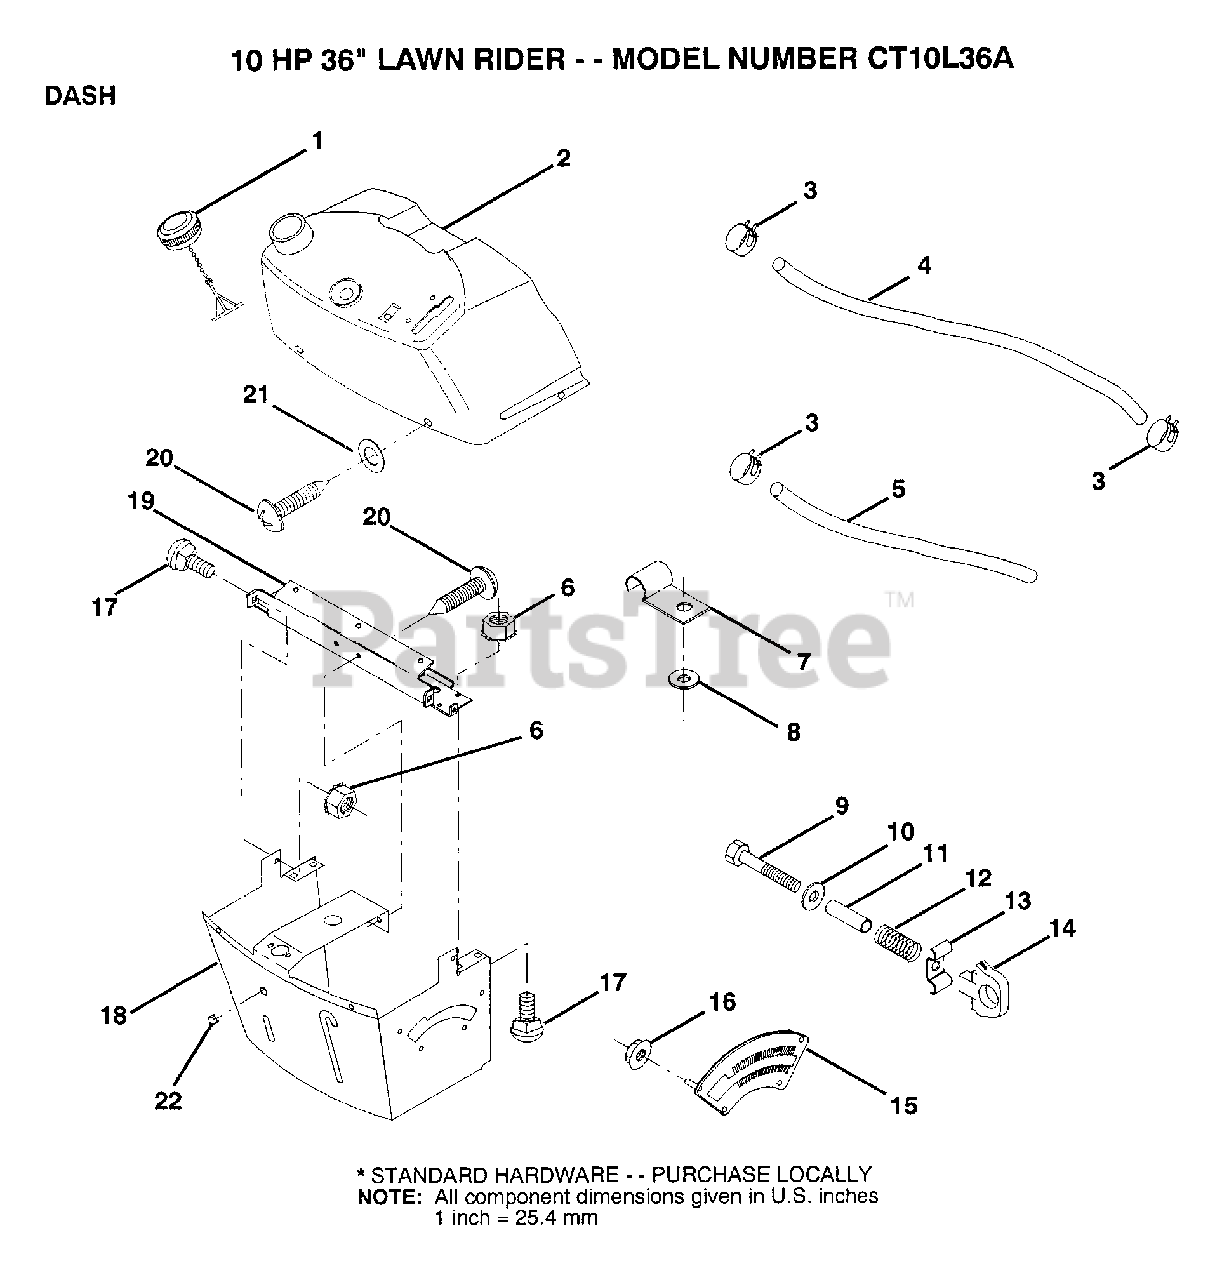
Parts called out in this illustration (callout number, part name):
3	HOSE CLAMP
5	FUEL LINE T
6	NUT
7	CLIP T
8	WASHER PM
9	BOLT
11	SPACER SPLIT
12	SPRING M
13	"KNOB,HGT RETAINER"
14	KNOB
15	ADJUSTER QUAD
16	NUT
17	BOLT
18	SUPT ASSY DASH
19	CROSS BRACE
22	PLUG DOME
